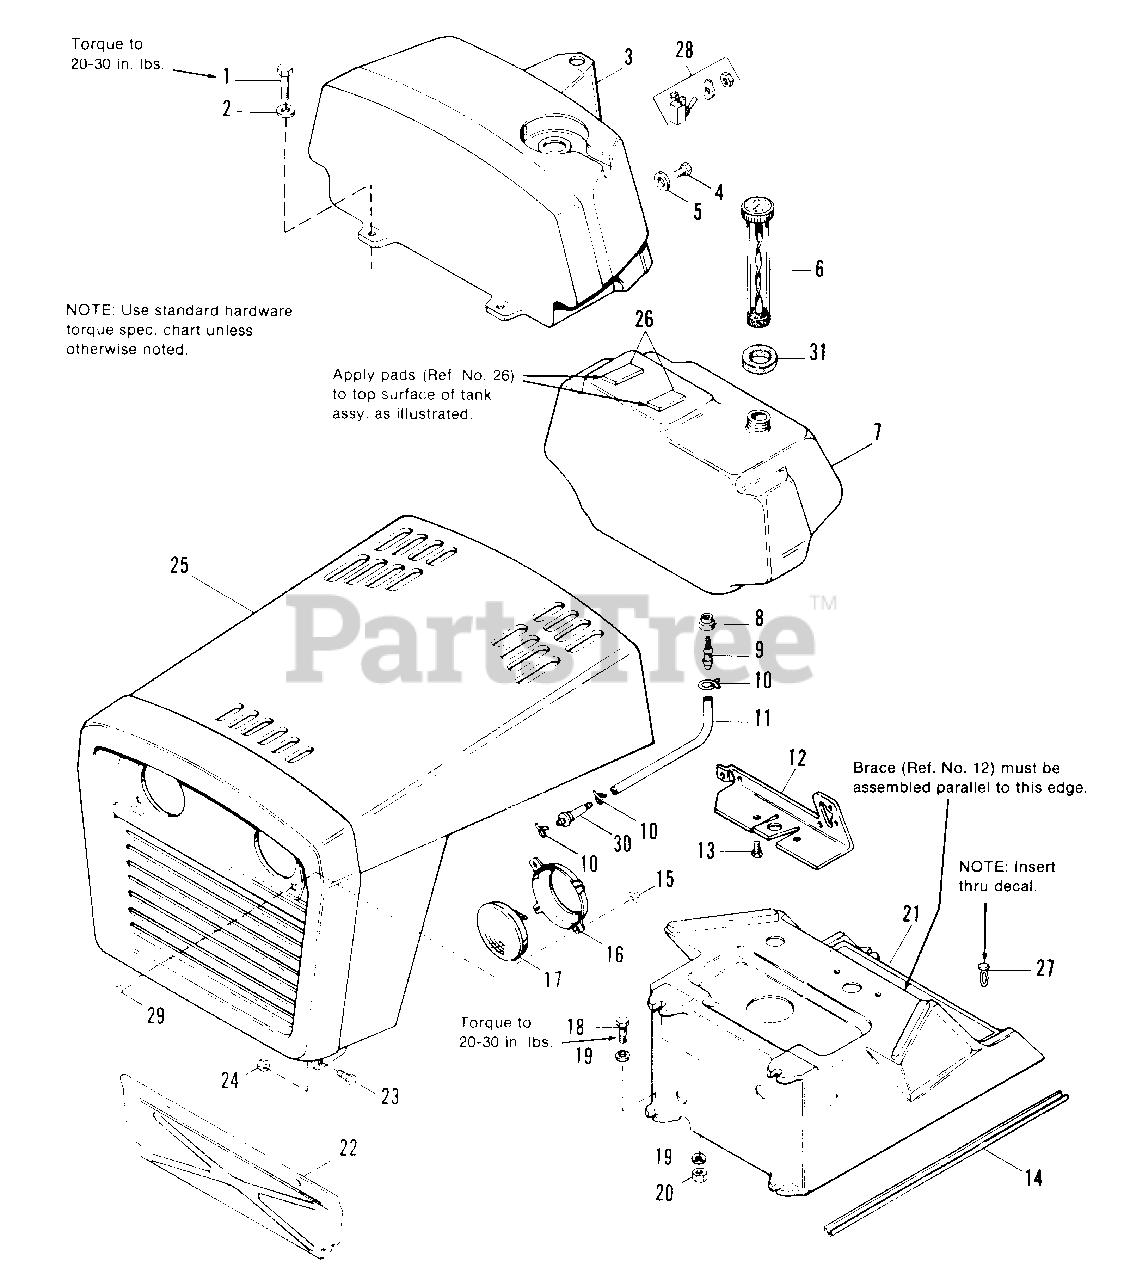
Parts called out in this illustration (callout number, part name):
1	CAPSCREW, Hex Hd., 1/4-20 x 1-1/4
2	WASHER, Plain, 1/4
3	DASHBOARD, Top
4	SCREW, #14 x 3/4
5	WASHER, Plain, 3/16
7	TANK ASSY., Fuel
10	CLAMP, Hose
12	BRACE, Dash
13	SCREW, Hex, Taptite, 1/4-20 x 1
14	EDGING, Lower Dash
15	LOCKNUT, Pal, #10-24
16	BRACKET, Support, Headlight
17	LAMP, Sealed Beam, G.E. #4411-1
18	SCREW, Hex, Taptite, 1/4-20 x 1
19	LOCKWASHER, Dished Type, 1/4
20	LOCKNUT, Hex, 1/4-20
21	DASHBOARD, Bottom
22	BAFFLE, Engine, Front (1691431, 1691558)
23	CAPSCREW, Hex Hd., 3/8-16 x 7/8
24	LOCKNUT, Hex, 3/8-16
25	HOOD & GRILLE ASSY.
27	CLIP, Canoe
28	SWITCH, Toggle
29	BOLT, Carriage, #10-24 x 1/2
30	FILTER, Fuel
31	FOAM WASHER
